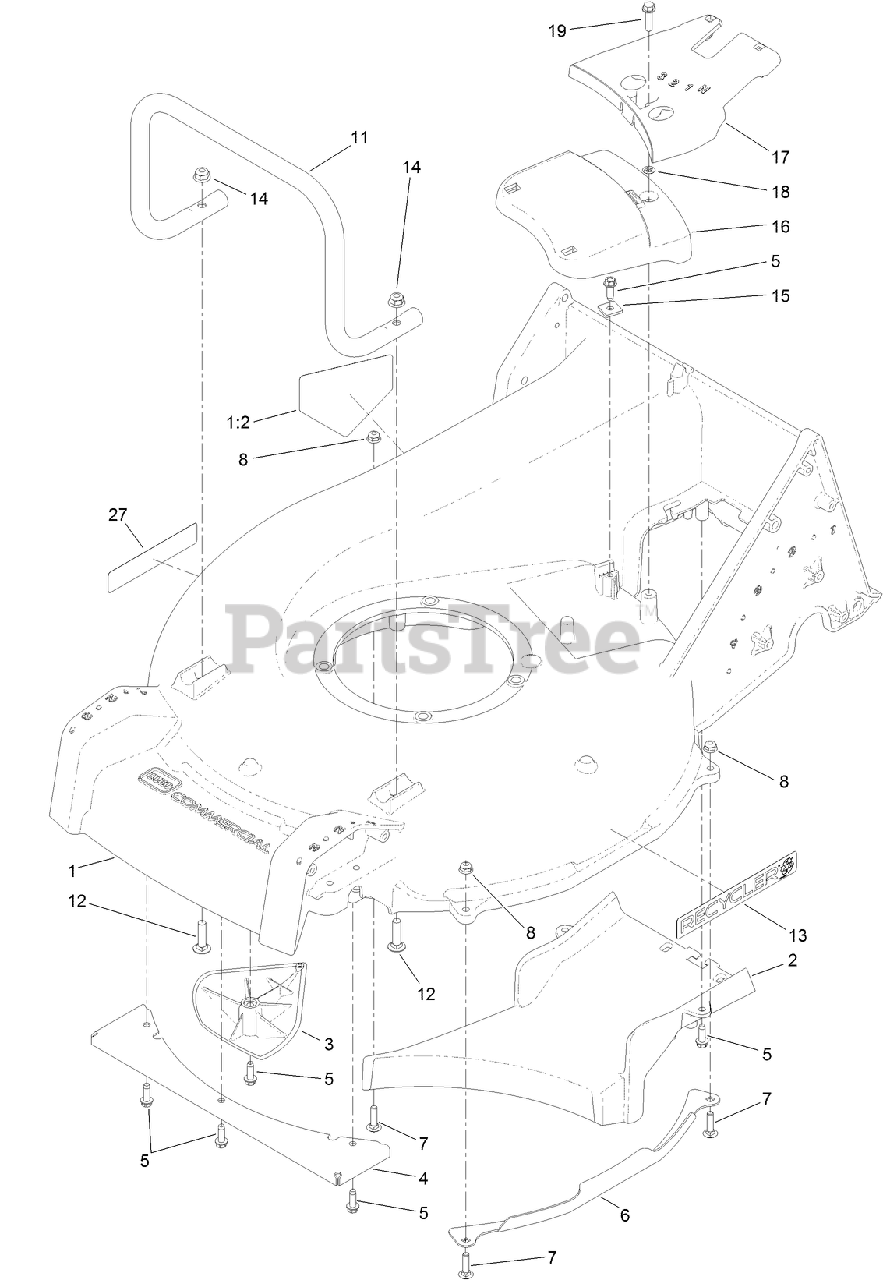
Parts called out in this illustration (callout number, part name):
1	HOUSING ASM
1:2	DECAL-DANGER
2	FLOOR-CHUTE
3	KICKER
4	GUARD-TOE, FRONT
5	SCREW-HWHTF
6	GUARD-SIDE, DECK
7	SCREW-CARR
8	NUT-HF
11	GUARD-ENGINE
12	SCREW-CARR
13	DECAL-RECYCLER
14	NUT-HF, NI
15	CLAMP-CABLE
16	COVER-BELT, FRONT
17	COVER-BELT, REAR
18	NUT-RETAINER
19	SCREW-HWHTF
